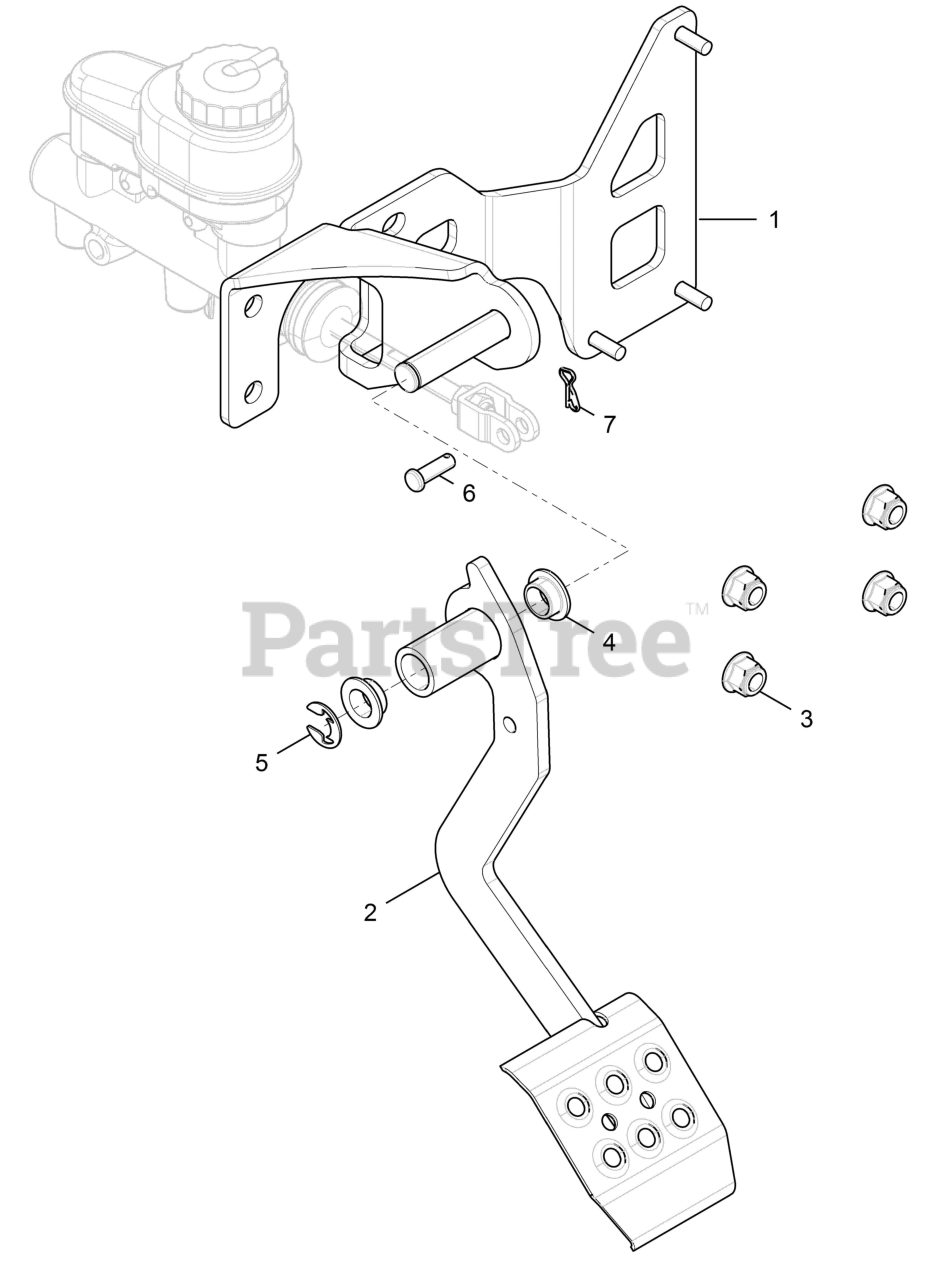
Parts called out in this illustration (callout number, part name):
1	WELD-PEDAL MOUNT,BLK
2	WELD-BRAKE PEDAL,MATTE'BLK
3	NUT-M8X1.25,FLG,NYLOC-OLIVE D
4	BUSHING-PEDAL PIVOT
6	PIN-CLEVIS, 1/4 X 3/4 -Y
7	PIN-CLIP,14MM
